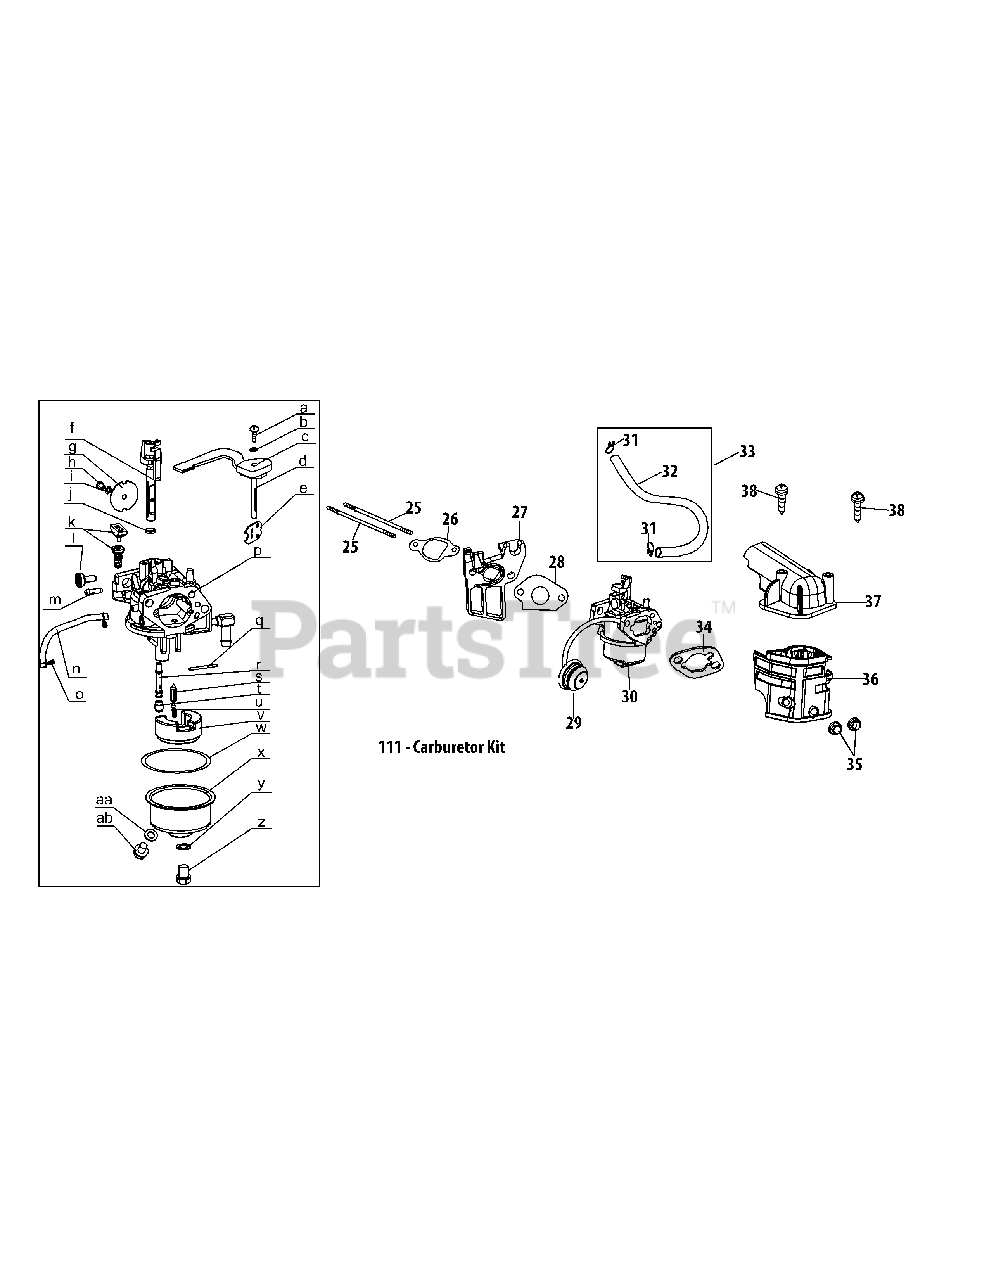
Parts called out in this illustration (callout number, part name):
25	Stud M6×110
26	Carburetor Insulator Gasket
27	Carburetor Insulator
28	Carburetor Gasket
29	Primer Assembly
29	Primer Bulb
30	Carburetor Assembly
31	Fuel Hose Clamp
32	Fuel Hose
33	Fuel Line Kit
34	Carburetor Gasket Plate
36	Air Cleaner Housing
37	Air Cleaner Assembly
38	Self-Tapping Bolt M4.2×45
111	Carburetor Kit
